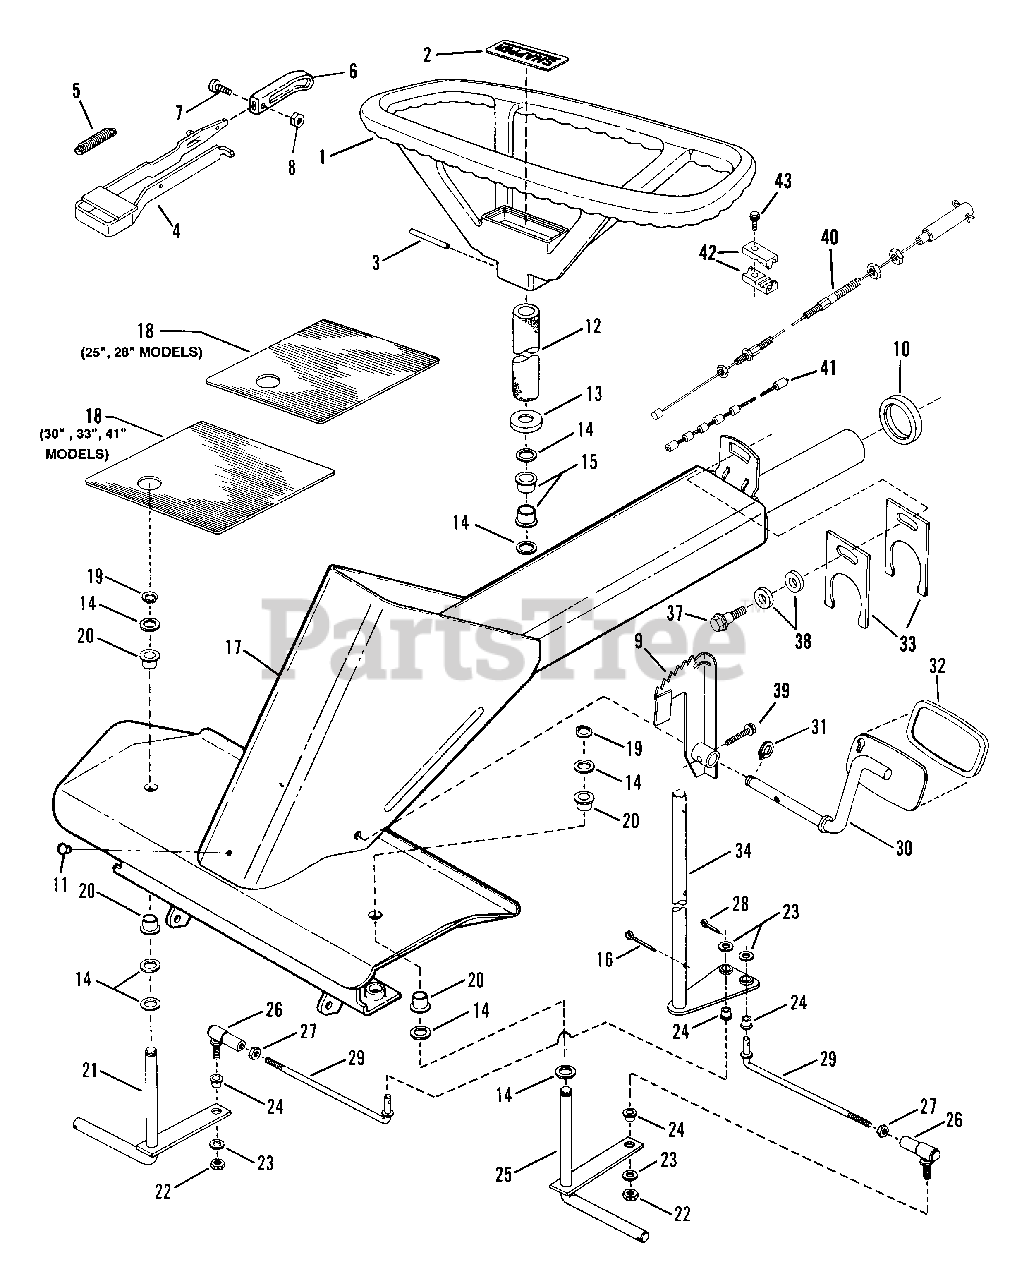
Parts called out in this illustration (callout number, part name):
1	ASSEMBLY, Steering Wheel
2	DECAL, Snapper
3	PIN, 1/4 x 1-1/2" Roll
4	BRACKET, Clutch/Brake
5	SPRING
6	KNOB
7	SCREW, #8-32 x 3/8" Cross Recess
8	NUT, #8-32 Hex
9	ARM, Clutch/Brake
10	SPACER, Main Tube
11	PLUG
12	COVER, Steering Shaft (Foam)
13	COVER
14	WASHER, 3/4 Flat
15	BUSHING, 3/4" Steering Shaft
16	PIN, 3/16 x 1-1/2" Cotter
17	FRAME, Front
18	PAD, Foot (Right Side Shown)
19	RING, Retaining
20	BEARING
21	King Pin, R.H.
22	NUT, 3/8-24 Hex Lock
23	WASHER, 3/8" Flat
24	BUSHING
25	King Pin, L.H.
26	BALL JOINT, 3/8-24 Thread
27	NUT, 3/8-24 Hex
28	PIN, 1/8 x 3/4" Cotter
29	TIE-ROD
30	PEDAL, Clutch/Brake
31	RING, 5/8" External Retaining
32	PAD, Clutch/Brake Pedal
33	SPACER, Pivot
34	SHAFT, Steering
37	BOLT, 3/8-24 x 5/8" Hex Shoulder
38	SPACER
39	SCREW, 5/16-18 x 1-1/4" Self-Tapping
40	CABLE, Brake
41	CABLE, Clutch
42	UNION, Cable
43	BOLT, 1/4-20 x 1/2" Hex Flange Lock
